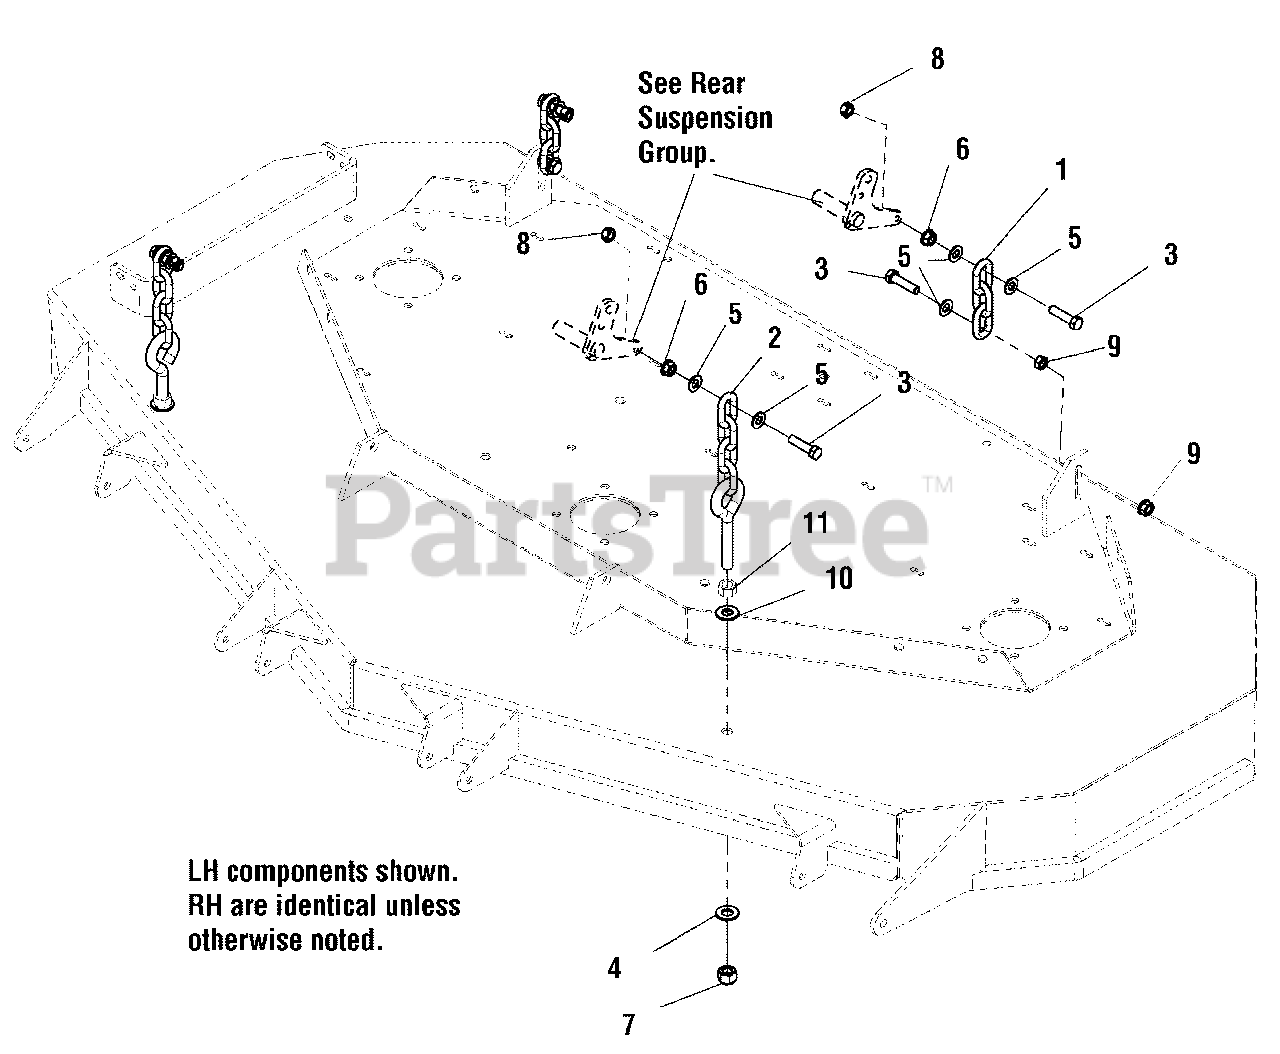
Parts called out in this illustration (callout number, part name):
1	CHAIN, 5/16" GD30, 3 LINKS
2	HANGER, FRONT DECK - 4 LINK, 5.5" EB
3	BOLT, 3/8-16 X 1-3/4" GD5
4	WASHER, 1/2" GD9 YZ
5	WASHER, 3/8" SAE
6	NUT, 3/8-16 HEX SERRATED FLANGE
7	NUT, 1/2-13 HEX NYLOCK FLANGE
8	NUT, 3/8-16 HEX SIDE LOCK
9	NUT, 3/8-16 HEX SERRATED FLANGE
10	WASHER, 1/2" SAE
11	NUT, 1/2-13 HEX
